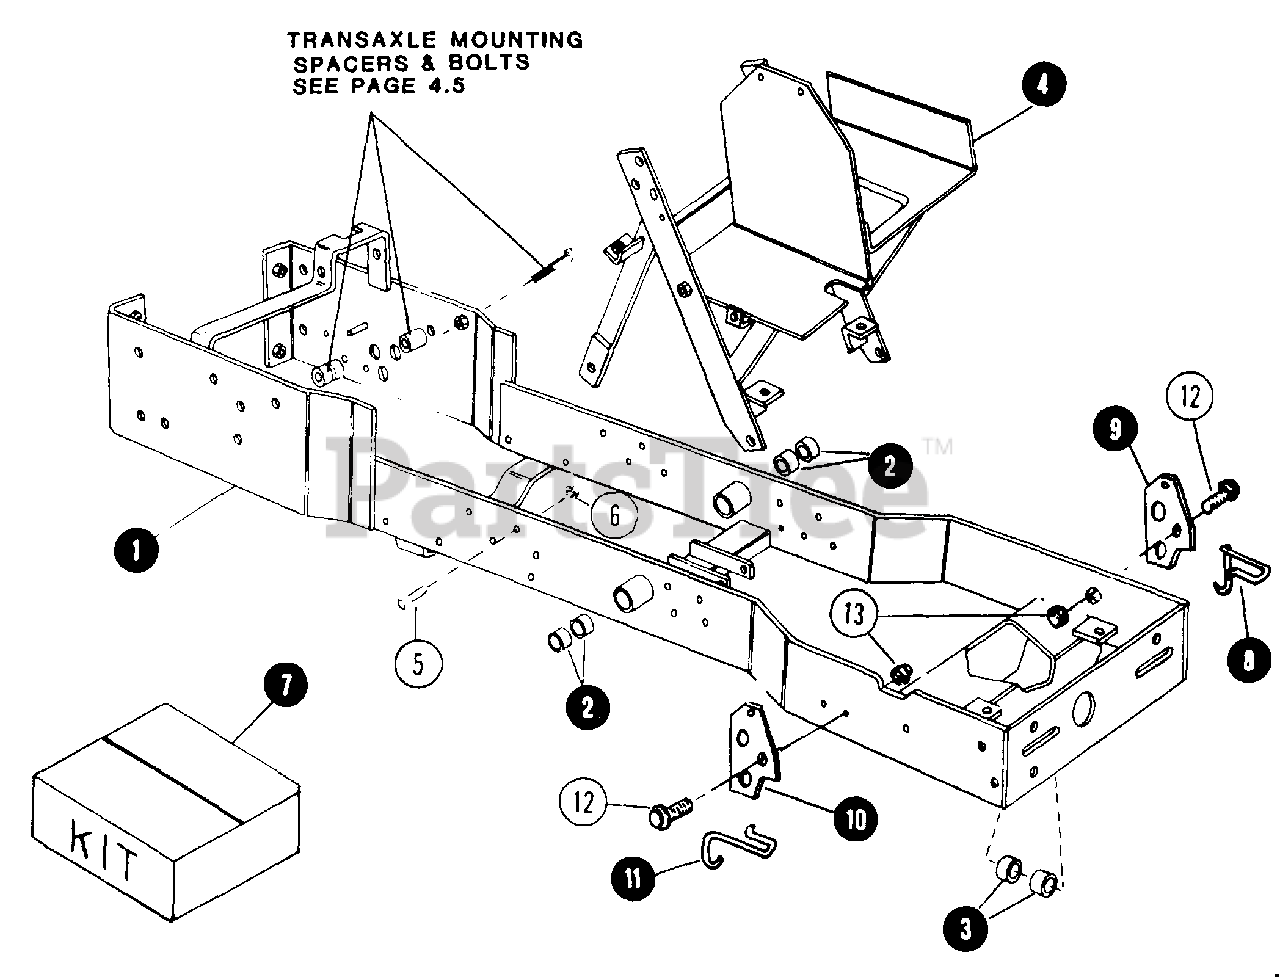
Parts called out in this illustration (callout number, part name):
1	MAIN FRAME ASSEMBLY
2	BUSHING, FRAME
3	BUSHING, FRAME
4	PEDESTAL FRAME
5	BOLT 3/8C x 1 HEX FLANGE
6	NUT 3/8C HEX FLANGE LOCK
7	KIT, IMPLEMENT MTG. BRACKET
8	BRACKET, LEFT SIDE
9	SPRING, LEFT SIDE
10	BRACKET, RIGHT SIDE
11	SPRING, RIGHT SIDE
12	BOLT, 3/8-16 x 1-1/4 HEX
13	NUT 3/8-16 HEX FLANGE LOCK
